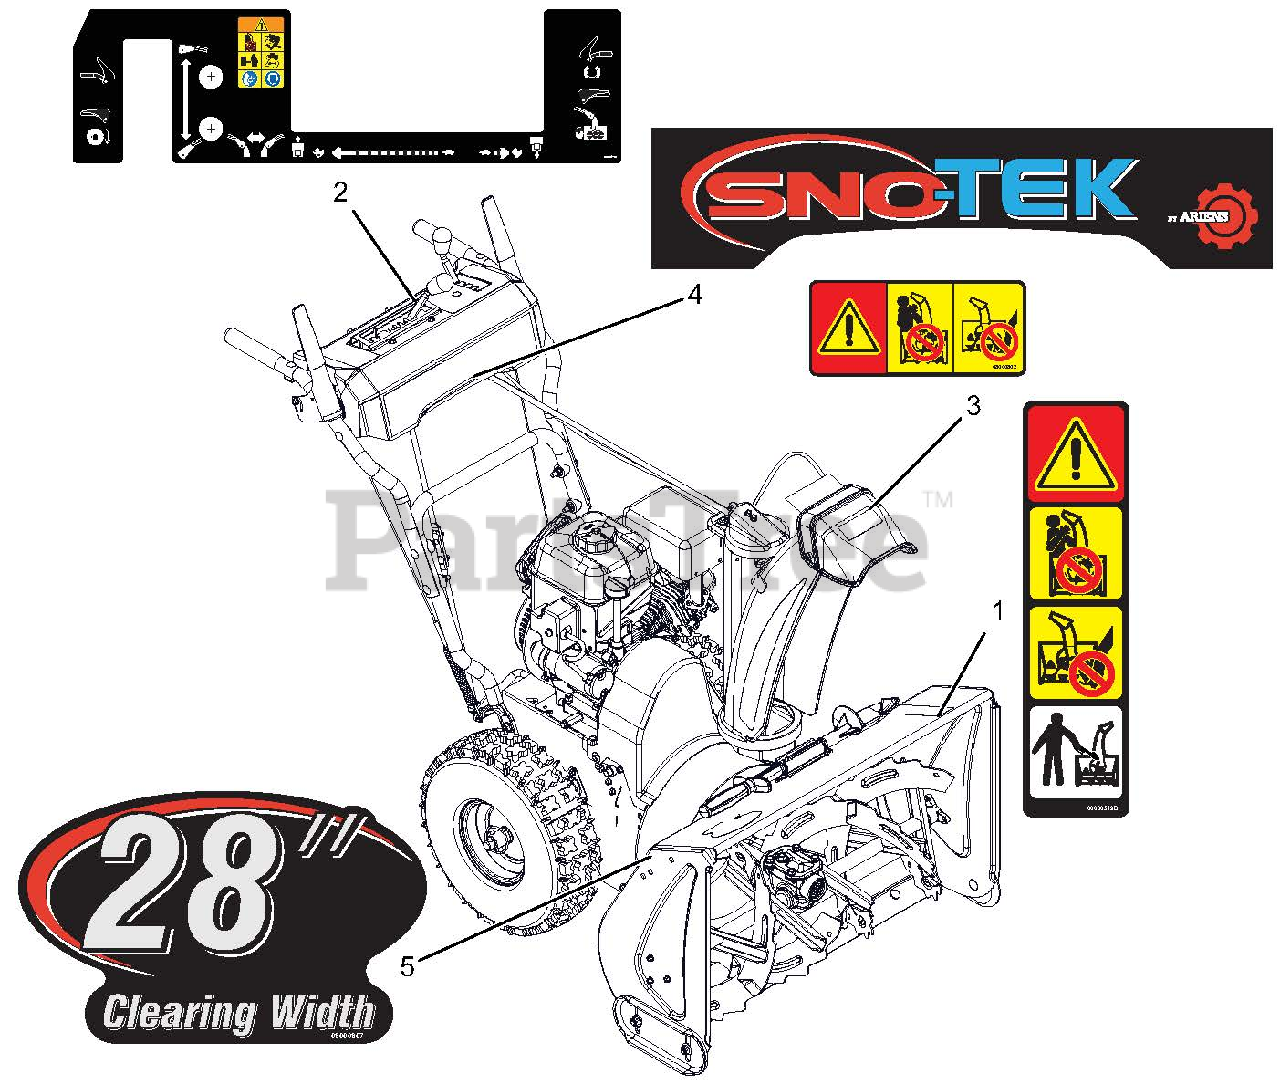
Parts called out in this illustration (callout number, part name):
1	DECAL, DANGER - ROTATING PARTS
2	DECAL,CONTROL - COMPACT REMOTE
3	DECAL, DANGER SNO-TEK
4	DECAL, DASH - SNO-TEK
5	DECAL, HOUSING SNO-TEK 28
